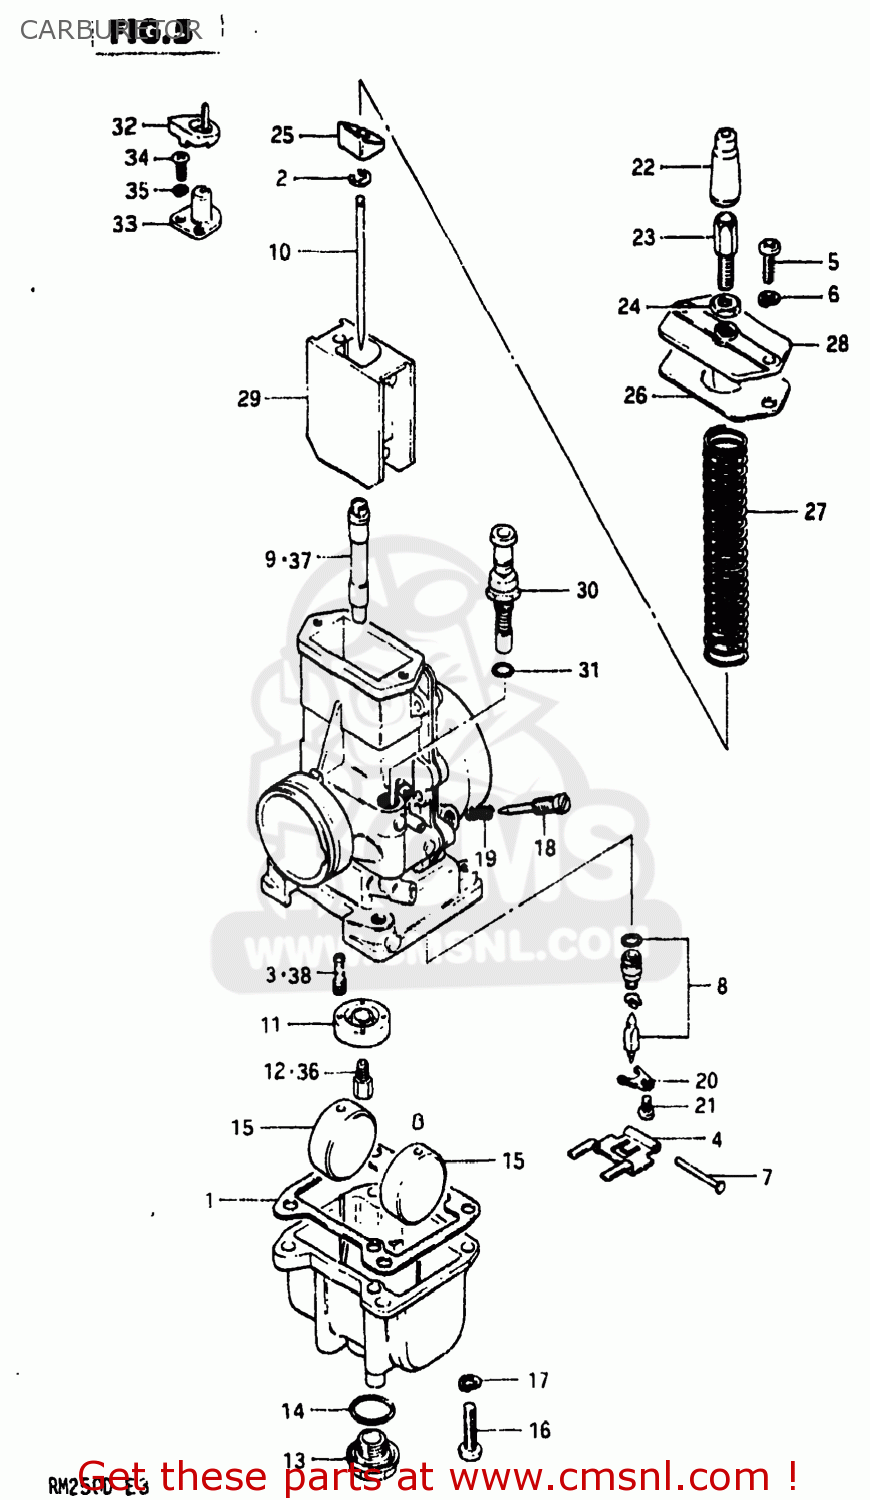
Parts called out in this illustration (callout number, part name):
0	CARBURETOR ASSEMBLY
1	GASKET,FLOAT CAHMBER (NAS)
2	CLIP
3	JET,PILOT
4	ARM,FLOAT
5	SCREW
6	LOCK WASHER
7	PIN,FLOAT
8	VALVE ASSEMBLY,NEEDLE
9	JET,NEEDLE
10	NEEDLE,JET
11	RING,MAIN JET FIXING
12	JET
13	SCREW,GUIDE
14	O RING,DRAIN PLUG
15	FLOAT
16	SCREW 5X20
17	LOCK WASHER
18	SCREW,PILOT AIR
19	SPRING
20	PLATE
21	SCREW 4X6
22	CAP,CABLE ADJUSTER
23	ADJUSTER,CABLE
24	NUT
25	SEAT,RETURN SPRING
26	GASKET,MIXING CHAMBER (NAS)
27	SPRING,THROTTLE VALVE
28	CAP,CARBURETOR,TOP
29	VALVE,THROTTLE
30	VALVE,STARTER
31	O-RING
32	RING
33	PLATE,NEEDLE JET
34	SCREW
35	LOCK WASHER
36	JET
37	JET,NEEDLE
38	JET,PILOT
